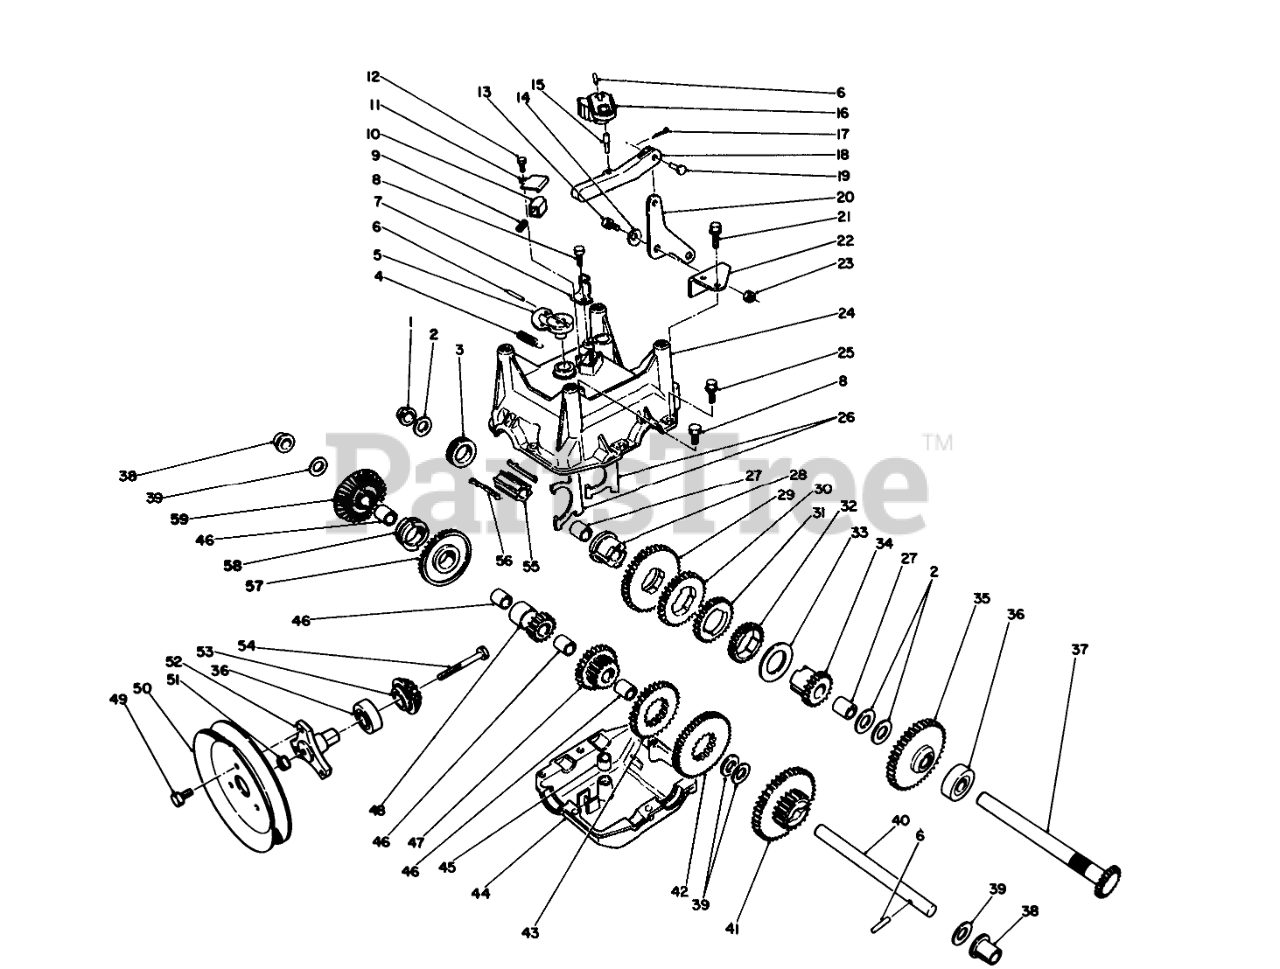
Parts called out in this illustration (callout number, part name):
1	BUSHING-FLANGE, OUTPUT
2	BEARING-THRUST
3	COLLAR-SHIFT
4	SPRING-EXTENSION
5	LEVER
6	PIN-SPRING
7	BRACKET-CABLE
8	SCREW-HWH
9	SPRING-DETENT
10	BUTTON-DETENT
11	COVER-DETENT
12	SCREW-HWH
13	SCREW-SHOULDER
14	WASHER-CURVED
15	PIN-LINK, GEAR SHIFT
16	LEVER-SHIFT, GEAR
17	PIN-COTTER
18	LINK-SHIFT, GEAR
19	PIN-CLEVIS
20	BELLCRANK
21	SCREW-HWH
22	BRACKET-BELLCRANK
23	NUT-LOCK, NI
24	GEARCASE-UPPER, CASING
25	SCREW-HWHTF
26	YOKE-SHIFT
27	BUSHING-OUTPUT
28	SLEEVE-GEAR
29	GEAR-45 T
30	GEAR-34 T
31	GEAR-27 T
32	GEAR-29 T
33	WASHER-THRUST
34	GEAR-SLEEVE, 19 T
35	GEAR-41 T
36	BEARING-BALL
37	SHAFT-OUTPUT
38	BUSHING-INTERMEDIATE
39	WASHER-THRUST
40	SHAFT-INTERMEDIATE
41	GEAR-19/41 T
42	GEAR-51 T
43	GEAR-33 T
44	GEARCASE-LOWER, CASING
45	BUSHING-YOKE
46	Bushing-Output
47	GEAR-26 T
48	GEAR-BEVEL, 15 T
49	SCREW
50	TRACTION-SHEAVE, HALF
51	NUT-HHF
52	HUB-PULLEY
53	PINION-BEVEL
54	SCREW-HH
55	SLEEVE-SHIFT
56	KEY-SHIFT
57	GEAR-BEVEL, 36 T
58	COLLAR-SHIFT
59	Gear-Bevel, Rev, 36 T
